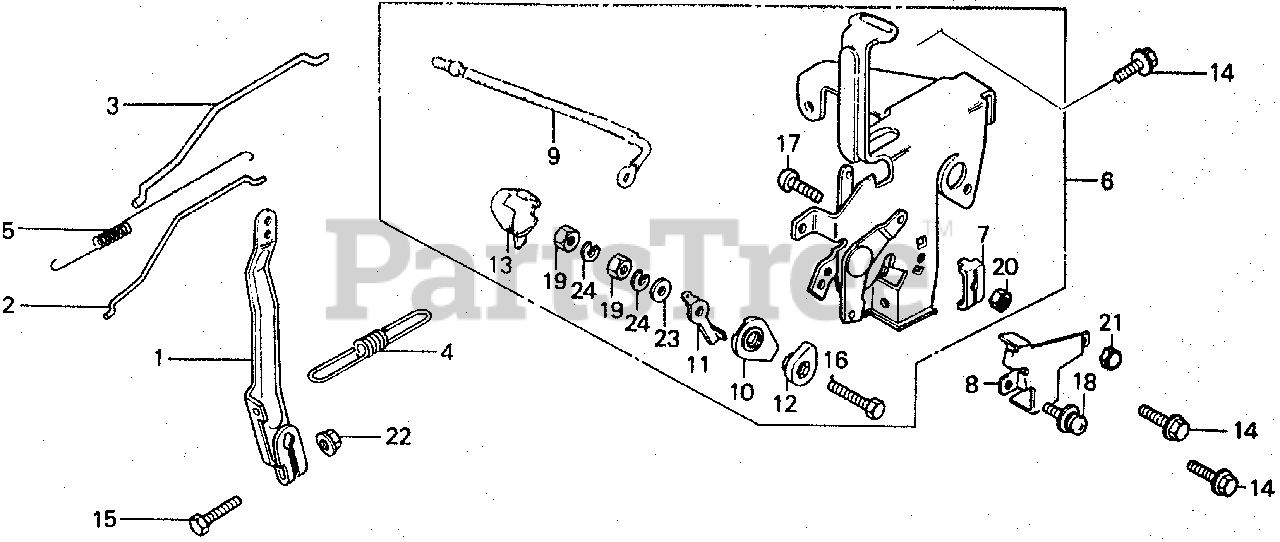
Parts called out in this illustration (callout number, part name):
1	ARM, GOVERNOR
2	ROD, GOVERNOR
3	ROD, CHOKE
4	SPRING, GOVERNOR (NOT AVAILABLE)
5	SPRING, THROTTLE RETURN
6	CONTROL ASSY. (NOT AVAILABLE)
7	HOLDER, CABLE
8	PROTECTOR, CONTROL
9	WIRE, STOP SWITCH (NOT AVAILABLE)
10	BASE, SWITCH (NOT AVAILABLE)
11	CONTACT, SWITCH (NOT AVAILABLE)
12	WASHER, INSULATOR (NOT AVAILABLE)
13	CAP, STOP SWITCH (NOT AVAILABLE)
14	BOLT, FLANGE (6X12) (CT200)
15	BOLT, GOVERNOR ARM
15	BOLT, HEX. (6X20)
16	BOLT, HEX. (4X20)
17	SCREW, PAN (5X22)
18	SCREW-WASHER (5X12)
19	NUT, HEX. (4MM)
20	NUT, HEX. (5MM)
21	NUT, CAP (5MM)
22	NUT, FLANGE (6MM)
23	WASHER, PLAIN (4MM)
24	WASHER, SPRING (4MM)
